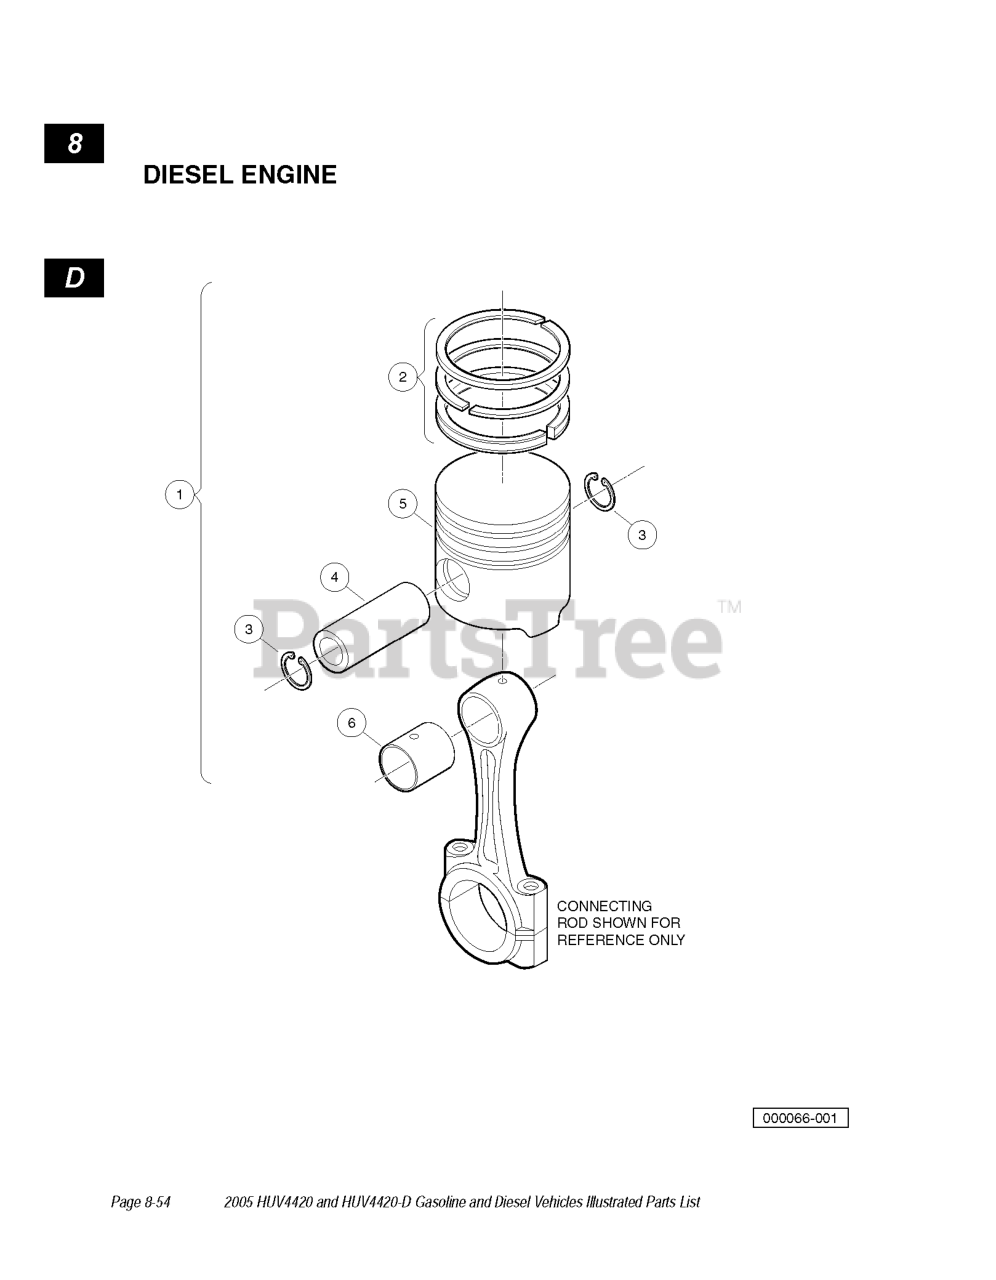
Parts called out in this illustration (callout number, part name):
1	KIT, PISTON REBUILD, D722
2	ASSY PISTON RING, D722 STD
3	CIRCLIP, PISTON PIN
4	PIN, PISTON
5	PISTON, D722, STD
6	BUSHING, PISTON PIN, D722
